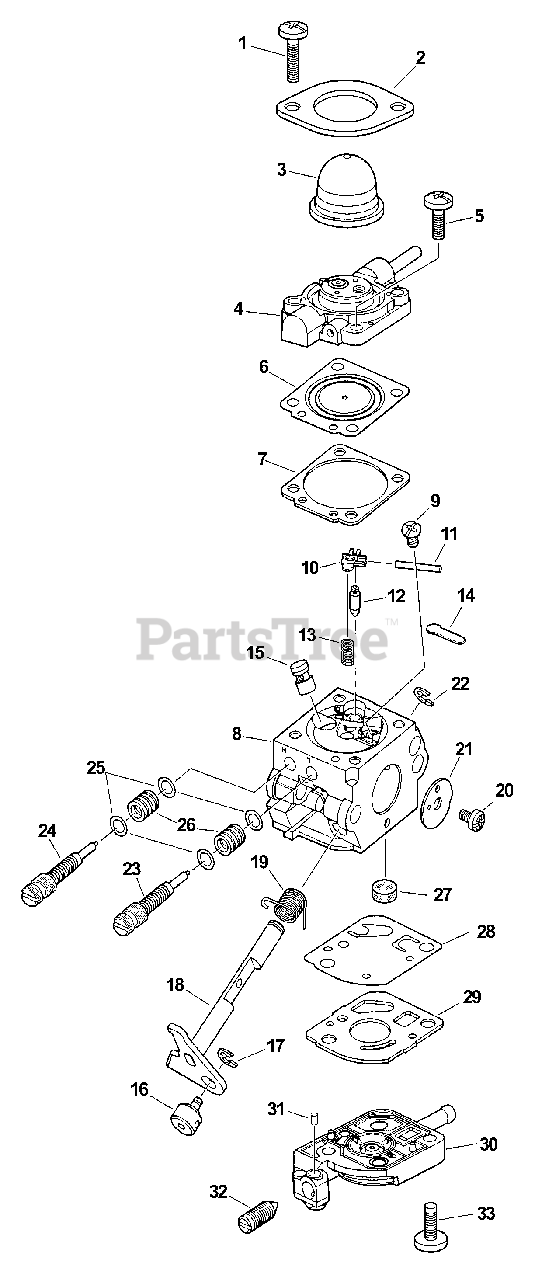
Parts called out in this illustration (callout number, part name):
1	SCREW
2	RETAINER, PURGE BULB
3	BULB, PURGE
4	BODY ASSY, PURGE
6	DIAPHRAGM, METERING
7	GASKET, METERING
8	BODY, CARBURETOR
10	LEVER, METERING
11	PIN, METERING LEVER
12	VALVE, INLET NEEDLE
13	SPRING, METERING LEVER
14	PLUG, WELCH
15	NOZZLE, CHECK VALVE
18	SHAFT, THROTTLE
19	SPRING, THROTTLE RETURN
21	VALVE, THROTTLE
23	NEEDLE, LOW SPEED
24	NEEDLE, HIGH SPEED
26	SPRING, NEEDLE
27	STRAINER
30	COVER, PUMP
31	PIECE, FRICTION
32	SCREW, IDLE ADJUST
